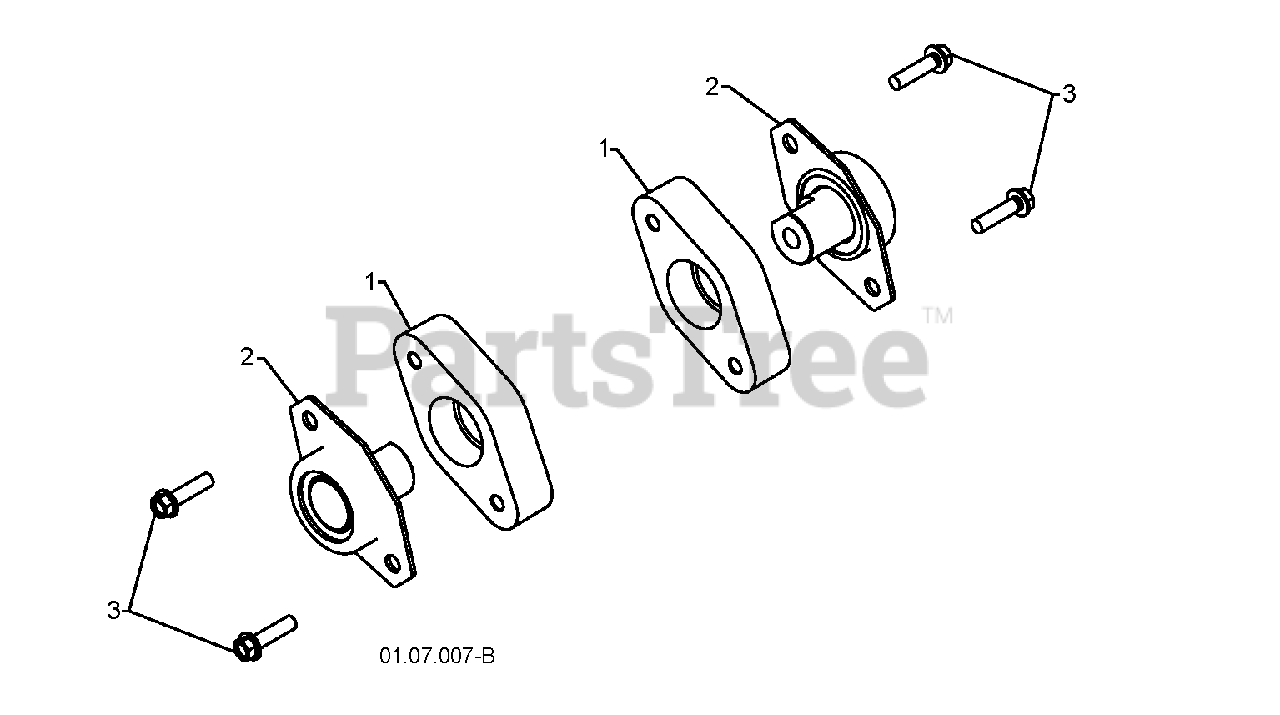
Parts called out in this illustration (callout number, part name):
1	RETAINER.PLASTIC
2	BEARING.BALL.AUGER
3	SCREW, HEX HD 5/16X1
